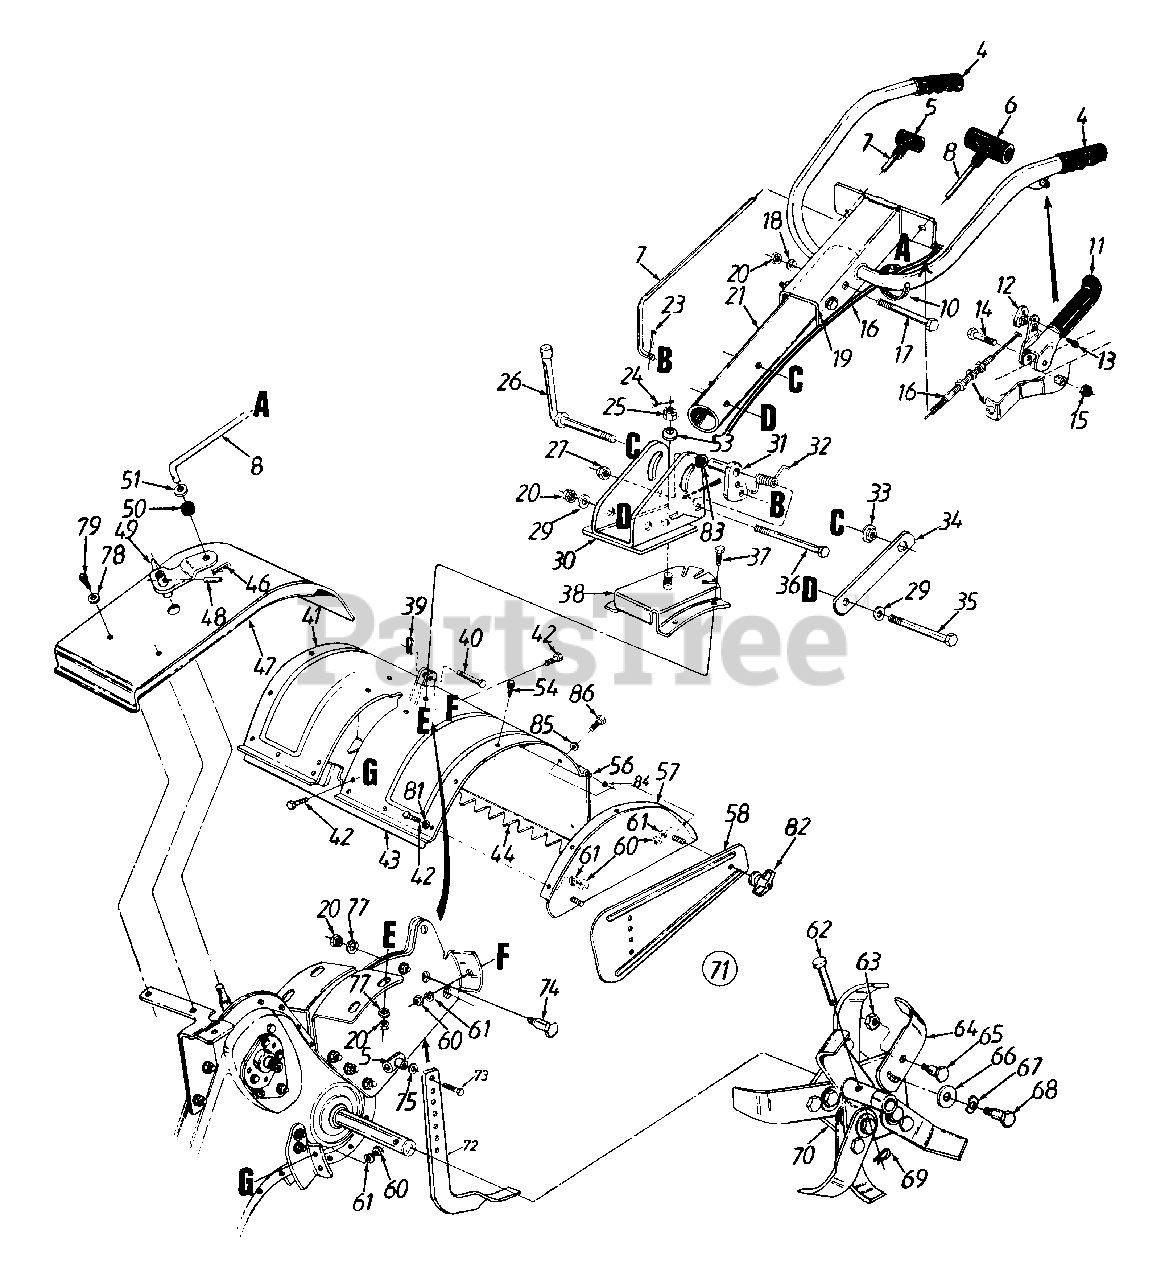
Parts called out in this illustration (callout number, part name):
4	Handle Grip
5	Small "T" Knob
6	Large "T" Knob
7	Clutch Rod
8	Control Rod 37" Lg.
10	Cable Tie-Self Clinching
12	Barrel Cable Hold Down
13	Hex B-Tap Scr. #10 x .44" Lg.
14	Hex Bolt 3/8-24 x 2.25" Lg.
15	Hex Jam L-Nut 3/8-24 Thd.
16	Clutch Control Cable 46" Lg.
17	Hex Bolt 3/8-16 x 3.00" Lg.
18	L-Wash. 3/8" I.D.-H.D.
19	Handle Ass'y.
20	Hex Nut 3/8-16 Thd.
24	Cotter Pin 3/32" Dia. x 1.25" Lg.
25	Hex Slotted Nut 5/8-18 Thd.
26	Handle Adj. Crank
27	Hex Cent. L-Nut 3/8-16 Thd.
29	Bell-Wash. .4" I.D. x .87" O.D.
30	Handle Pivot Bracket
31	Handle Link
32	Spring Handle Adj.
33	Hex Flange Nut 3/8-24 Thd.
34	Bracket Hex Nut Retainer
35	Hex Bolt 3/8-16 x 3.25" Lg.
36	Hex Bolt 3/8-16 x 3.00" Lg.-Gr. 8
37	Hex Bolt 3/8-16 x 1" Lg.
38	Handle Positioner Brkt. Ass'y.
39	Intern. Cotter Pin
40	Clevis Pin .375" Dia.
41	Tine Shield 18"
42	Hex Bolt 5/16-18 x 1" Lg.
43	Bracket Reinforcement-18"
46	Intern. Cotter Pin 5/16" Dia.
47	Shift Cover
48	Spring Roll Pin 3/16" Dia.
49	Shifting Crank Ass'y.
50	Rubber Washer .33" I.D.
51	Fl-Wash. .4" I.D. x 1.25" O.D.
53	Bell-Wash. .63" I.D. x 1.25"
54	Hex Wash. Tap Scr.
56	Tiller Flap Rod
57	End Cover Ass'y.
58	Side Shield
60	Hex Nut 5/16-18 Thd.
61	L-Wash. 5/16" I.D.
62	Clevis Pin .375" Dia.
63	Hex Nut 3/8-24 Thd.
65	Shld. Bolt 1/2" Dia. x .175
66	Fl-Wash. .51" I.D. x 1.50"
67	Bell-Wash. .515" I.D. x 1.14"
68	Shld. Bolt 1/2" Dia. x .320
69	Intern. Cotter Pin
73	Hex Bolt 3/8-16 x 1" Lg.
74	Shld. Bolt 1/2" I.D. x .62" Lg.
75	Fl-Wash. 3/8" I.D. x 5/8" O.D.
77	L-Wash. 3/8" I.D.
78	Fl-Wash. .281" I.D. x .62"
79	Hex Wash. Self-Tap Scr. 1/4-20 x .50" Lg.
82	Plastic Knob 5/16-18 Thd.
83	Fl-Wash. .406" I.D. x .875" O.D.
84	End Cap
85	Flat Washer
86	Shoulder Screw
